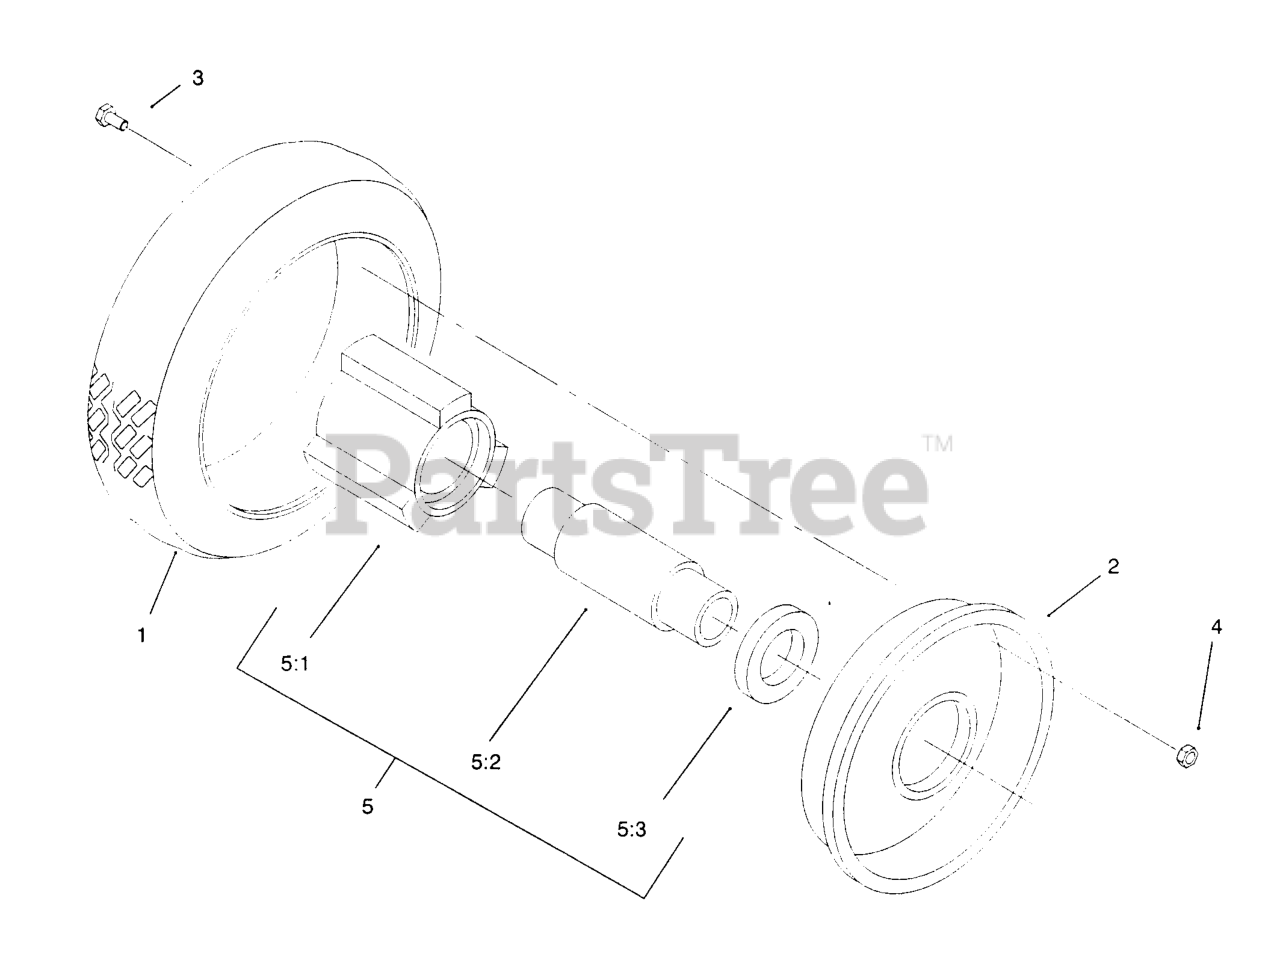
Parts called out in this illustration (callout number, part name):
3	SCREW-HH
4	NUT-LOCK, NI
5	Hub & Bearing Asm
5:1	HUB-BEARING
5:2	SPACER-BEARING
5:3	BEARING-WHEEL
